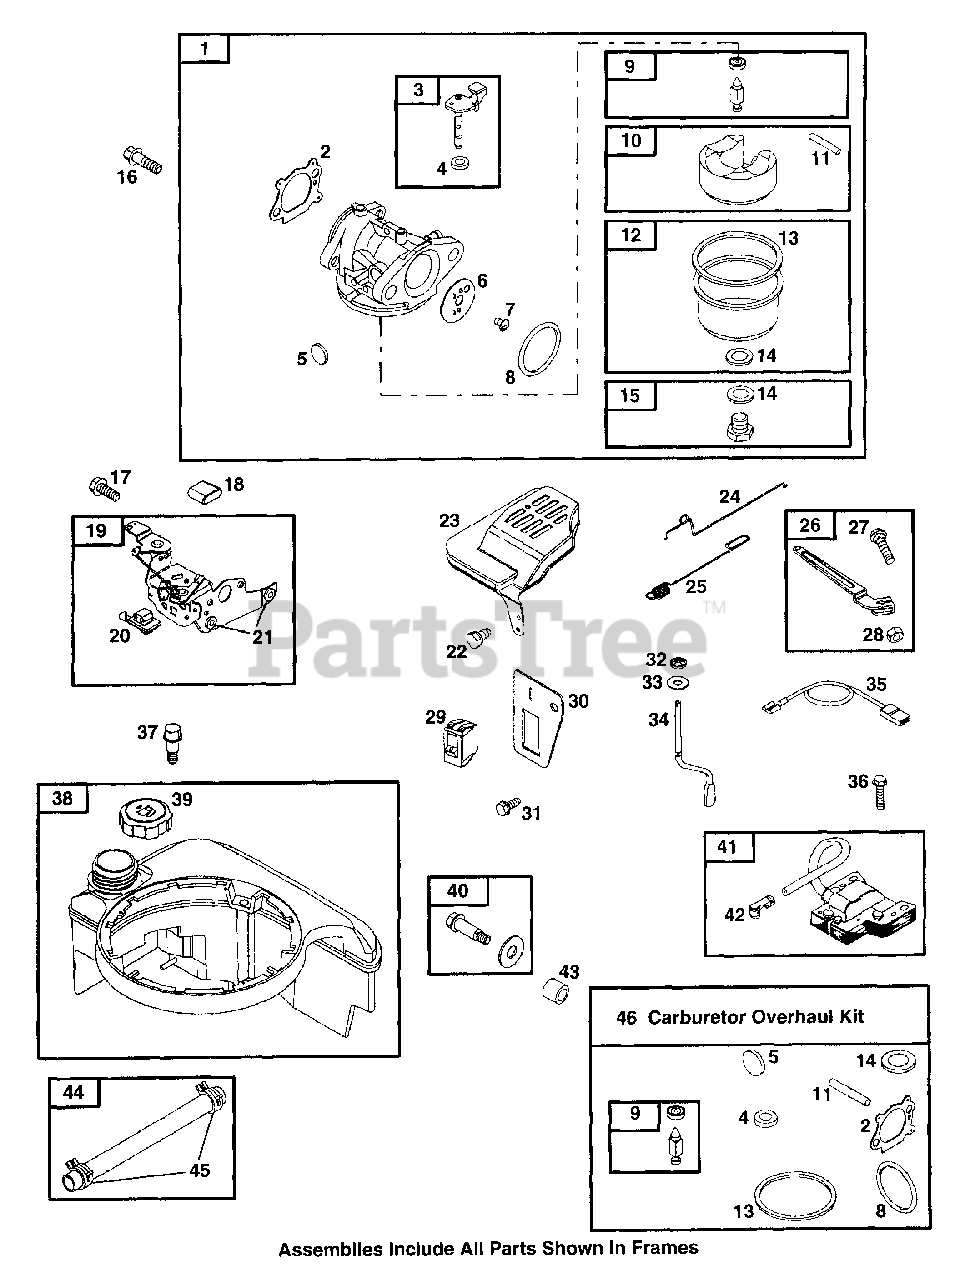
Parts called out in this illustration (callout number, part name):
1	Carburetor
2	Air Cleaner Gasket
3	Throttle Shaft
4	Throttle Shaft Seal
5	Welch Plug
6	Throttle Valve
7	Screw (Throttle Valve)
8	O-Ring Seal (Intake Manifold)
9	Needle/Seat Kit
10	Carburetor Float
11	Float Hinge Pin
12	Float Bowl
13	Float Bowl Gasket
14	Sealing Washer
15	Main Jet (Standard)
16	Screw (Carburetor)
17	Screw (Control Bracket)
18	Sleeve Lever
19	Control Bracket
20	Stop Switch
21	Spacer
22	Screw (Control Cover)
23	Control Cover
24	Mechanical Governor Link
25	Governor Spring
26	Governor Control Lever
27	Bolt (Governor Control Lever)
28	Nut (Governor Control Lever)
29	Rocker Switch
30	Stop Switch Bracket
31	Screw (Stop Switch Bracket)
32	Retainer Governor Shaft
33	Washer (Governor Crank)
34	Governor Crank
36	Screw (Magneto Armature)
37	Screw (Fuel Tank)
38	Fuel Tank
39	Fuel Tank Cap
40	Screw/Washer Kit
41	Magneto Armature
42	Sparkplug Terminal
43	Fuel Tank Spacer
44	Fuel Line
45	Hose Clamp
46	Carburetor Overhaul Kit
